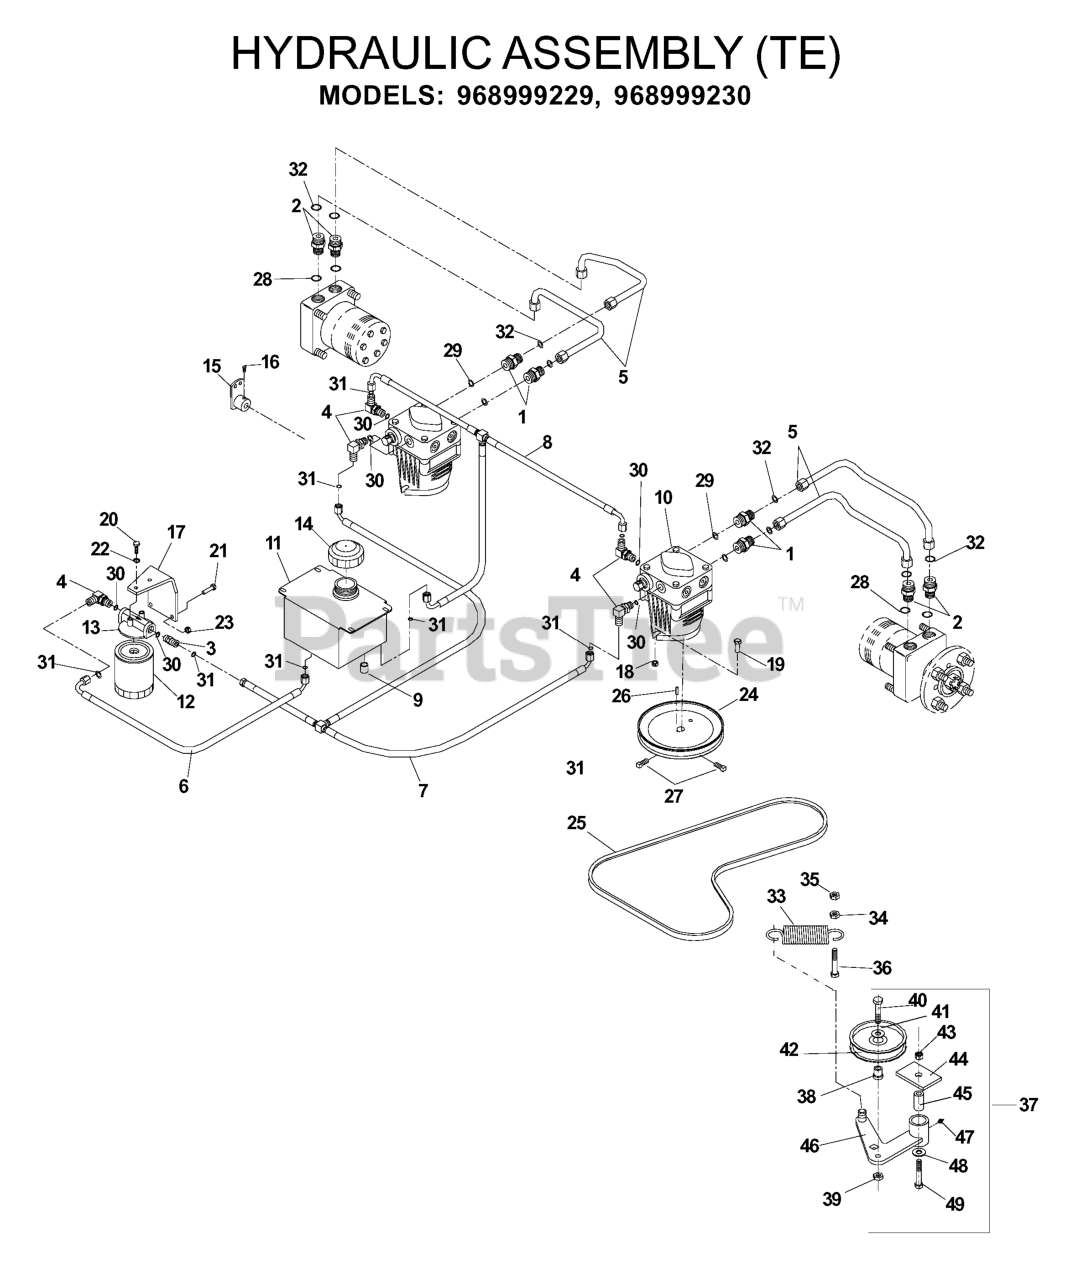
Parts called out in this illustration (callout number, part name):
1	FITTING, STRAIGHT F6400-8-8-0
3	STRAIGHT FITG
4	ELBOW, F6801-6-6-0 90 DEGREE
5	HYDRAULIC HOSE
7	TEE ASSEMBLY
8	TEE ASSEMBLY
9	NUT 9/16-18 JIC CAP
10	HG_PUMP
12	HYDRAULIC OIL FILTER
13	FILTER HEAD
14	HYDRAULIC CAP
15	PUMP LEVER
16	5/16C X 5/8 "V" POINT
17	OIL FILTER BRKT
18	NUT 3/8C CENTERBLOCK
19	4CS 3/8C X 1 SERRATED HEAD
20	HCS 1/4C X 5/8
21	HCS 1/4C X 3/4 HCS
22	LOCKWASHER 1/4"
23	NUT.1/4-20.HEX.NYLOC.ZD
25	PUMP BELT
26	KEY 5 MM SQ X 25 MM
27	SCREW 5/16C X 5/8 SQ HEAD
34	NUT 3/8C WHIZ
35	NUT 3/8-16 NYLOC
36	HCS 3/8C X 2
37	TORSION SPRING
38	BUSHING, IDLER FLANGE
39	NUT 3/8C CENTERBLOCK
40	HCS 3/8-16 X 1 3/4 GR5
41	WASHER 3/8 FLAT
42	IDLER PULLEY
43	NUT 1/2-13 HEX NYLOC ZD
45	PIVOT BUSHING
46	IDLER ARM WLDT
47	ZERK
48	WASHER 1/2 FLAT
49	HCS 1/2C X 3 1/4
